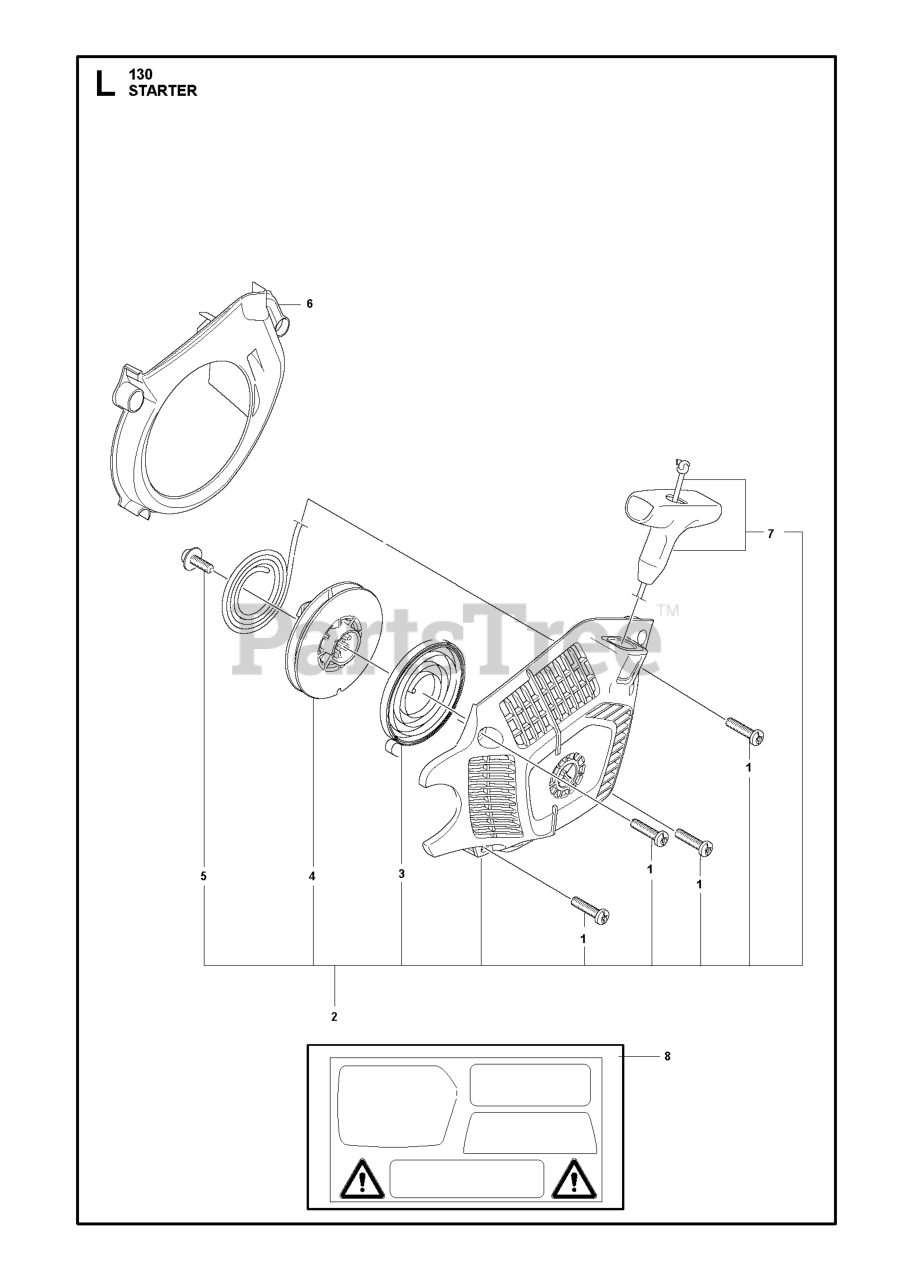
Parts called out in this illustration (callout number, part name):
1	SCREW M5.38-14X22.225MM
2	SERVICE KIT STARTER HOUSING
4	PULLEY 130 CHAINSAW
6	BAFFLE 130 CHAINSAW
7	STARTER ROPE W/HANDLE
8	SERVICE KIT DECAL
